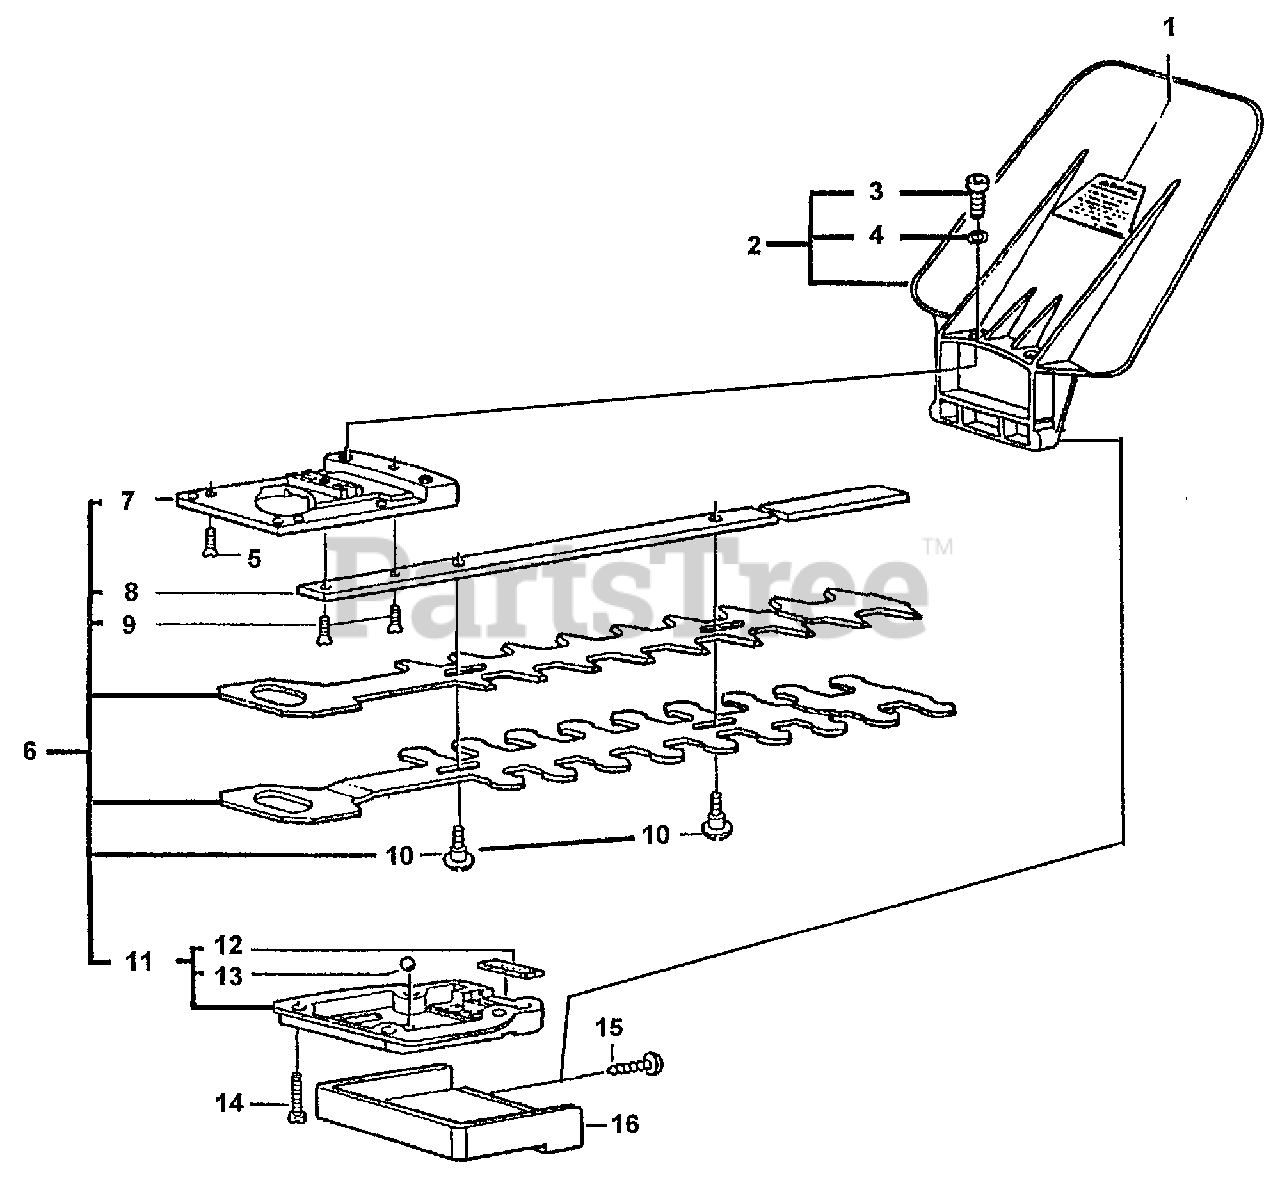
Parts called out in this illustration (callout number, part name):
1	LABEL - CAUTION
2	GUARD ASSY
4	WASHER, SPRING
5	SCREW
6	BLADE ASSY
7	FLANGE
8	STIFFENER, BLADE - 26"
10	SCREW
11	LID, GEAR CASE
12	PACKING, FELT
13	BALL - 4
15	SCREW 4×16
